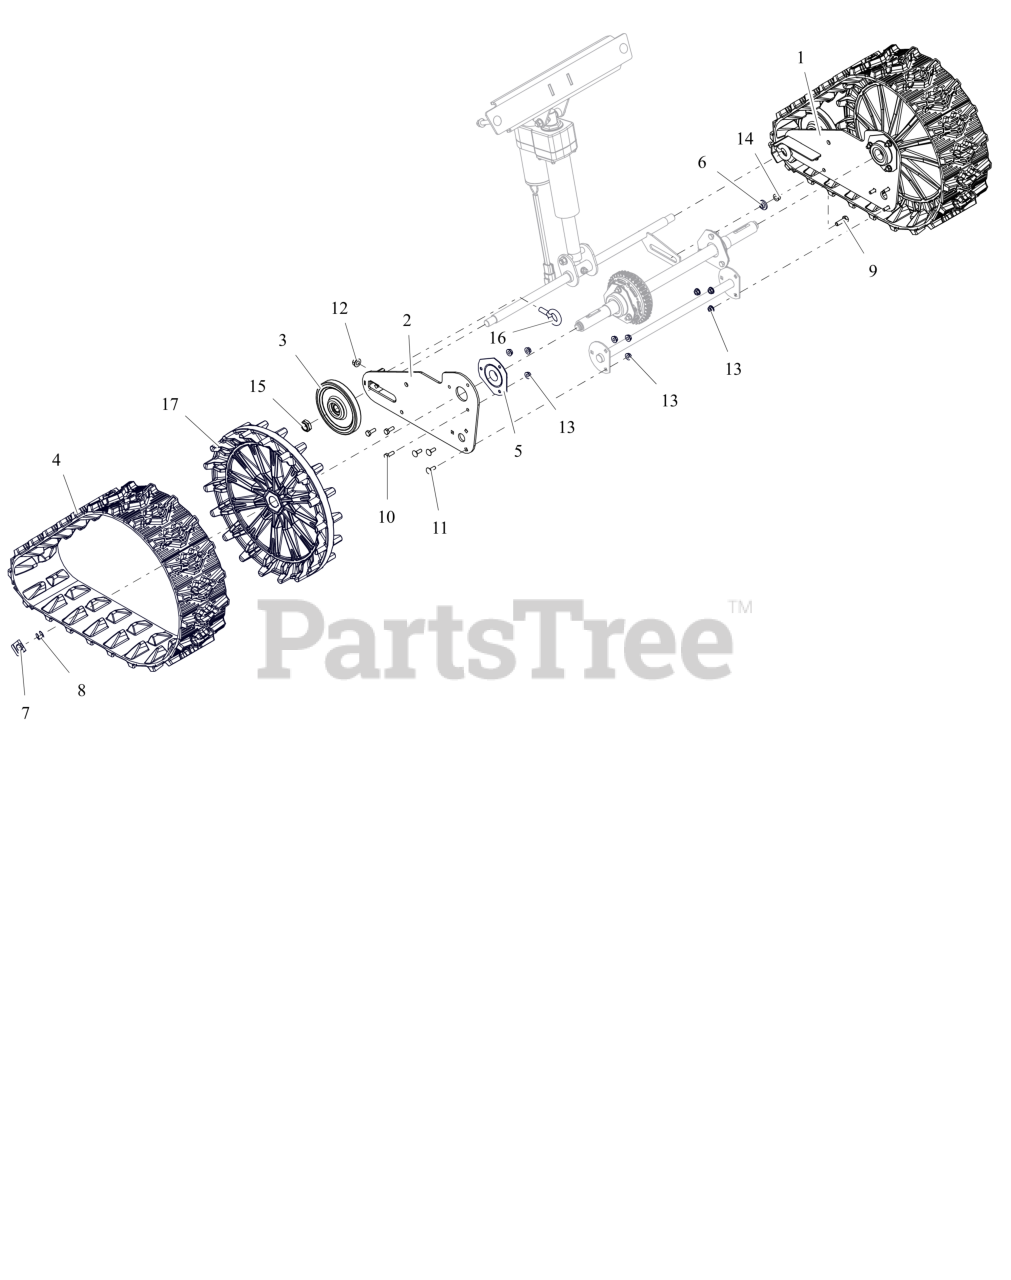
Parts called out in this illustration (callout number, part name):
1	PLATE, SIDE-BWT LH WLDMT
2	PLATE, SIDE-BWT RH WLDMT
3	WHEEL, BOGIE - SINGLE BEARING
4	TRACK, RUBBER - 22 PITCHES
5	BRG-FLG 1.003/1.000 3 BOLT
6	BSHG-FLG .325X.499X.3X.875
7	CLIP, SNAP .625 DIA
8	RG-RTNG-EXT .625X.042
9	BLT,HEX .31-18X1.00 G5 ZCC
10	BLT, HEX .25-20X.75 G5 ZCC
11	BLT, RHSN .25-20X.750 G5 ZCC
12	NUT-LK-CTR-FLG .375-16 GF ZCC
13	NUT-LK-TOP-FLG .250-20 GF ZCC
14	NUT-LK-TOP-FLG .312-18 GF ZCC
15	NUT, NYL LK .625-18 ZCC
16	BLT-EYE .375-16X.880 YWZC
17	SPROCKET, LARGE TRACK DRIVE
